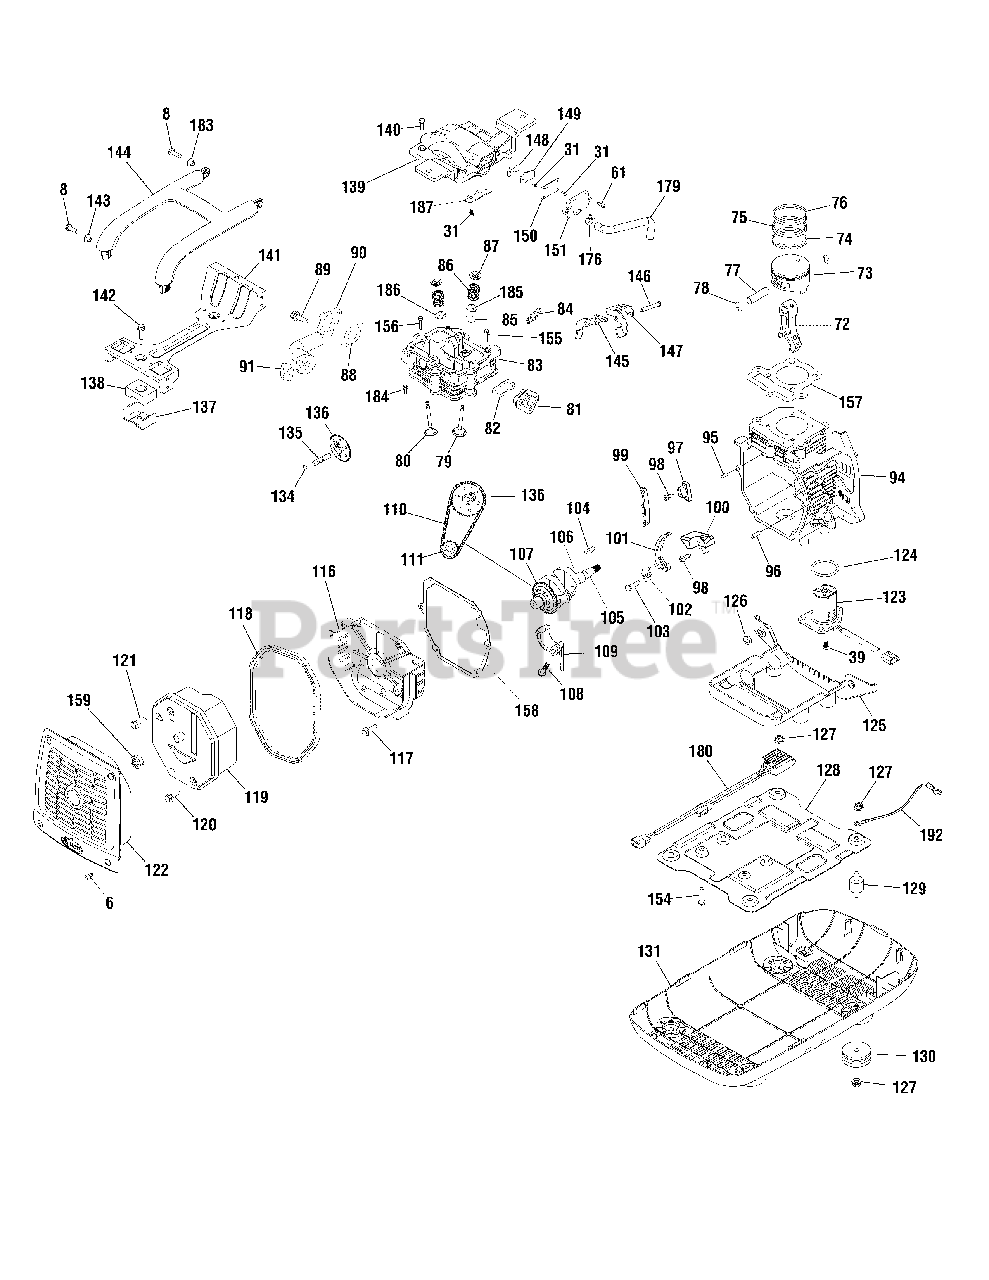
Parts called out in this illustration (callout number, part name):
31	BOLT
61	SCREW
72	ROD
73	PISTON
74	RING
75	RING
76	RING
77	PIN
78	RETAINER-PIN
79	VALVE-INTAKE
80	VALVE-EXHAUST
83	CYLINDER HEAD
85	SEAL-VALVE OIL
86	SPRING
87	SEAT-VALVE
89	BOLT
90	MUFFLER
94	CRANKCASE
95	PIN
96	PIN
97	BLOCK
98	SCREW
99	BRACKET
100	BRACKET
101	ARM-TENSION
102	SPRING
103	PIN
104	KEY
105	CRANKSHAFT
106	BEARING
107	GEAR
108	BOLT
109	COVER
110	CHAIN
111	WHEEL-CHAIN
116	COVER-CRANKCASE
117	BOLT
118	BLOCK-RUBBER
119	MUFFLER
120	BOLT
121	BOLT
122	GUARD-MUFFLER
125	COVER
126	NUT
129	MOUNT-VIBRATION
130	MOUNT-VIBRATION
134	O-RING
135	SHAFT
136	CAM-ASSEMBLY
137	BRACKET
138	MOUNT-VIBRATION
140	BOLT
141	BRACKET
142	BOLT
145	ARM-EXHAUST VALVE
146	PIN
147	ARM-INTAKE VALVE
150	BOARD-VALVE
151	BOARD-VALVE
154	BOLT
155	BOLT
156	BOLT
157	GASKET
158	GASKET-CRANKCASE
176	CLAMP
180	REGULATOR-VOLTAGE
184	BOLT
185	SEAT
186	SEAT
187	PLATE
